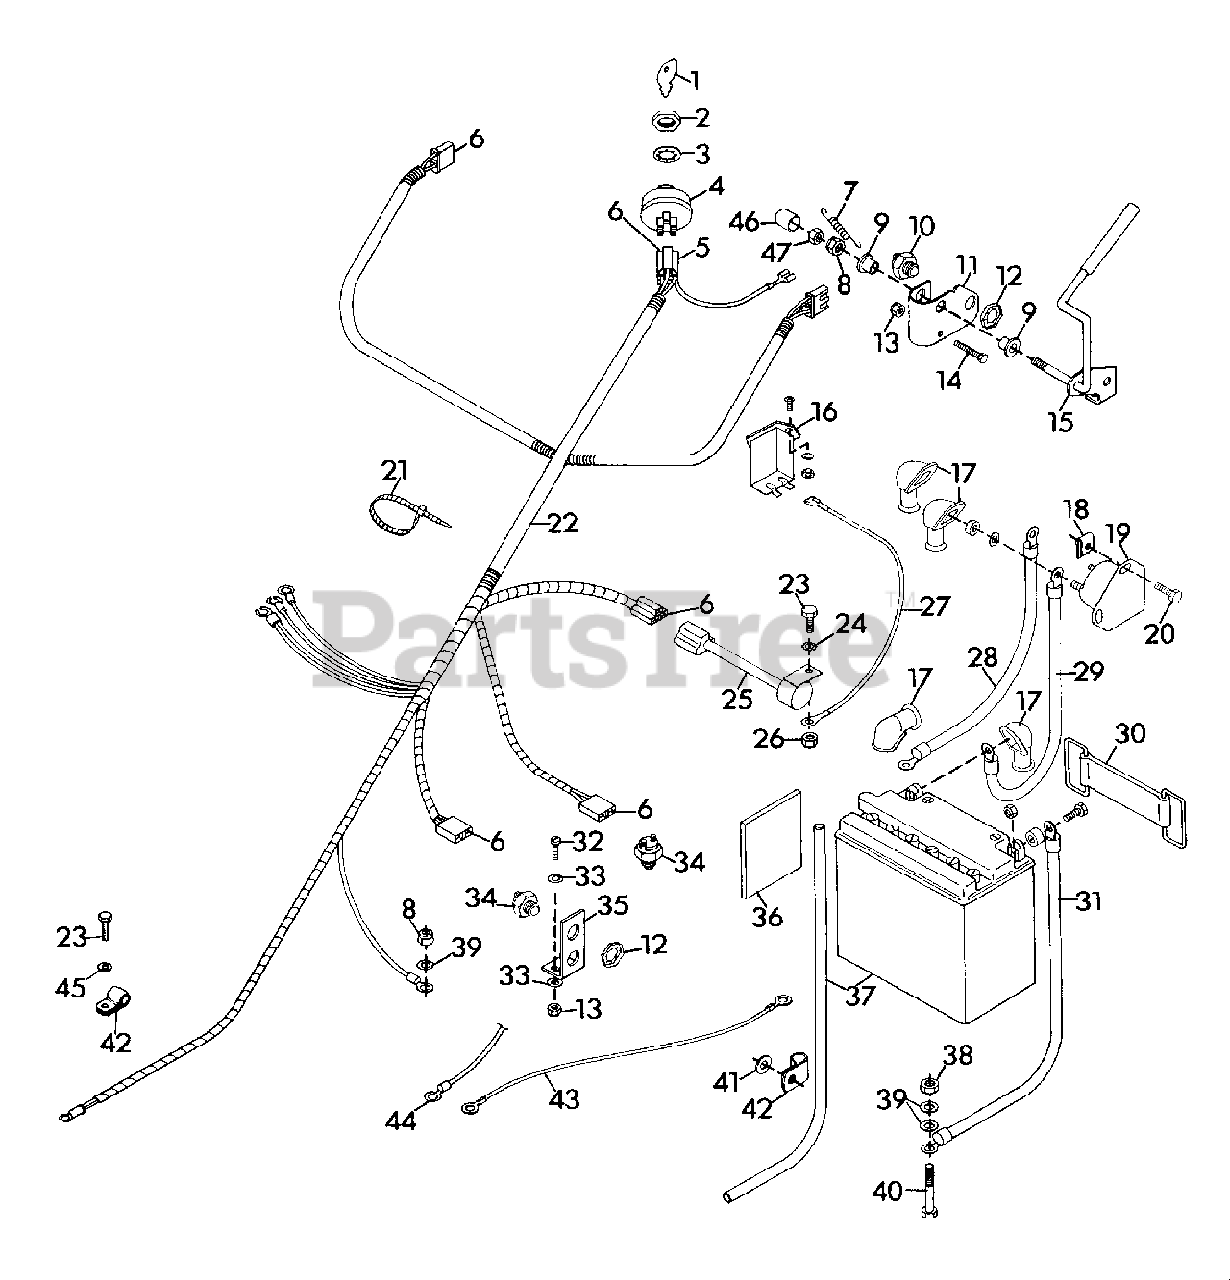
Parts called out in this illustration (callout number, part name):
1	KEY, IGNITION SWITCH
2	NUT, JAM 9/16-24
3	WASHER, LOCK
4	SWITCH, IGNITION
5	CONNECTOR
6	TERMINAL
7	SPRING, INTERLOCK LEVER
8	NUT, LOCK 5/16-18
9	BUSHING, INTERLOCK LEVER
10	SWITCH, INTERLOCK
11	BRACKET, INTERLOCK ACTUATING
12	NUT, STAMPED 9/16-18
13	NUT, LOCK 10-24
14	SCREW, MACHINE 10-24X1.50 HEX PHD
15	LEVER, PRESENCE CONTROL
16	HOURMETER
17	BOOT, BATTERY CABLE
18	NUT, SPEED 1/4-20
19	SWITCH, MAGNETIC
20	BOLT, HEX 1/4-20X.750
21	TIE, CABLE
22	HARNESS
23	BOLT, HEX 1/4-20X.625
24	WASHER, LOCK 1/4 EXT TH TYA
25	MODULE, INTERLOCK ELECTRIC
26	NUT, LOCK 1/4-20
27	WIRE, INSTRUMENT PANEL
28	CABLE, SOLENOID TO STARTER
29	CABLE, BATTERY TO SOLENOID
30	STRAP, BATTERY
31	CABLE, NEGATIVE BATTERY
32	SCREW, MACHINE 10-24X.75 PHD
33	WASHER, FLAT .188X.438X.049
34	SWITCH, NEUTRAL START
35	BRACKET, INTERLOCK SWITCH
36	PAD, BATTERY 3.5X4.0
37	BATTERY, 12 VOLT
38	NUT, HEX 5/16-18
39	WASHER, FLAT .344X.688X.065
40	BOLT, HEX 5/16-18X2.00
41	WASHER, FLAT .375X1.125X.065
42	CLAMP
43	WIRE, GROUND
44	TERMINAL, RING TONGUE
45	WASHER, FLAT .281X.625X.065
46	CLOSURE, VINYL
47	NUT, LOCK 5/16-18
